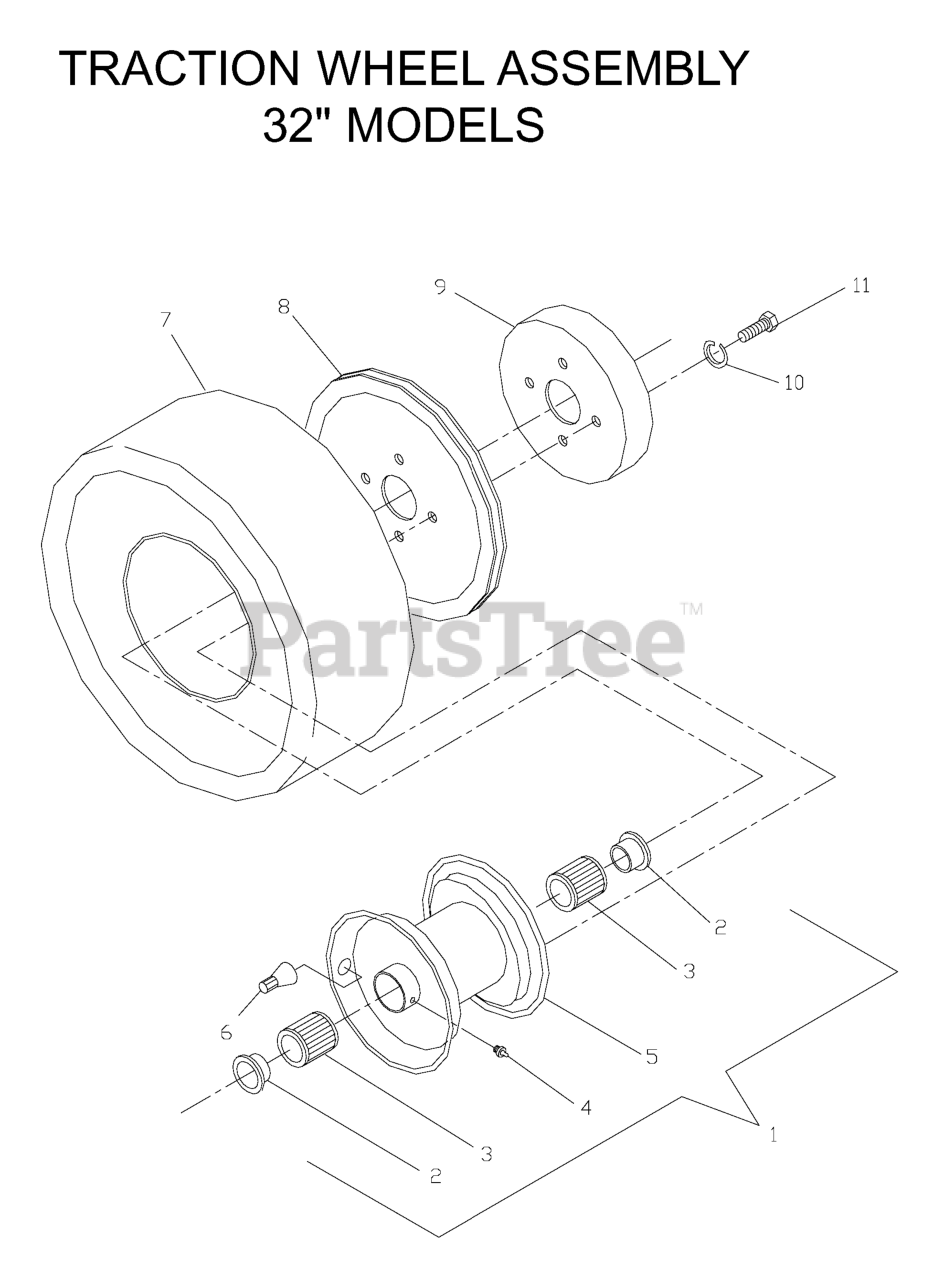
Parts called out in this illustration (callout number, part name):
2	BEARING FLANGE
3	ROLLER BEARING (LONG)
4	ZERK
6	VALVE STEM TR-412
8	TRACTION PULLEY
9	BRAKE DRUM
10	SLW 3/8 STD
11	HCS 3/8F X 3/4
